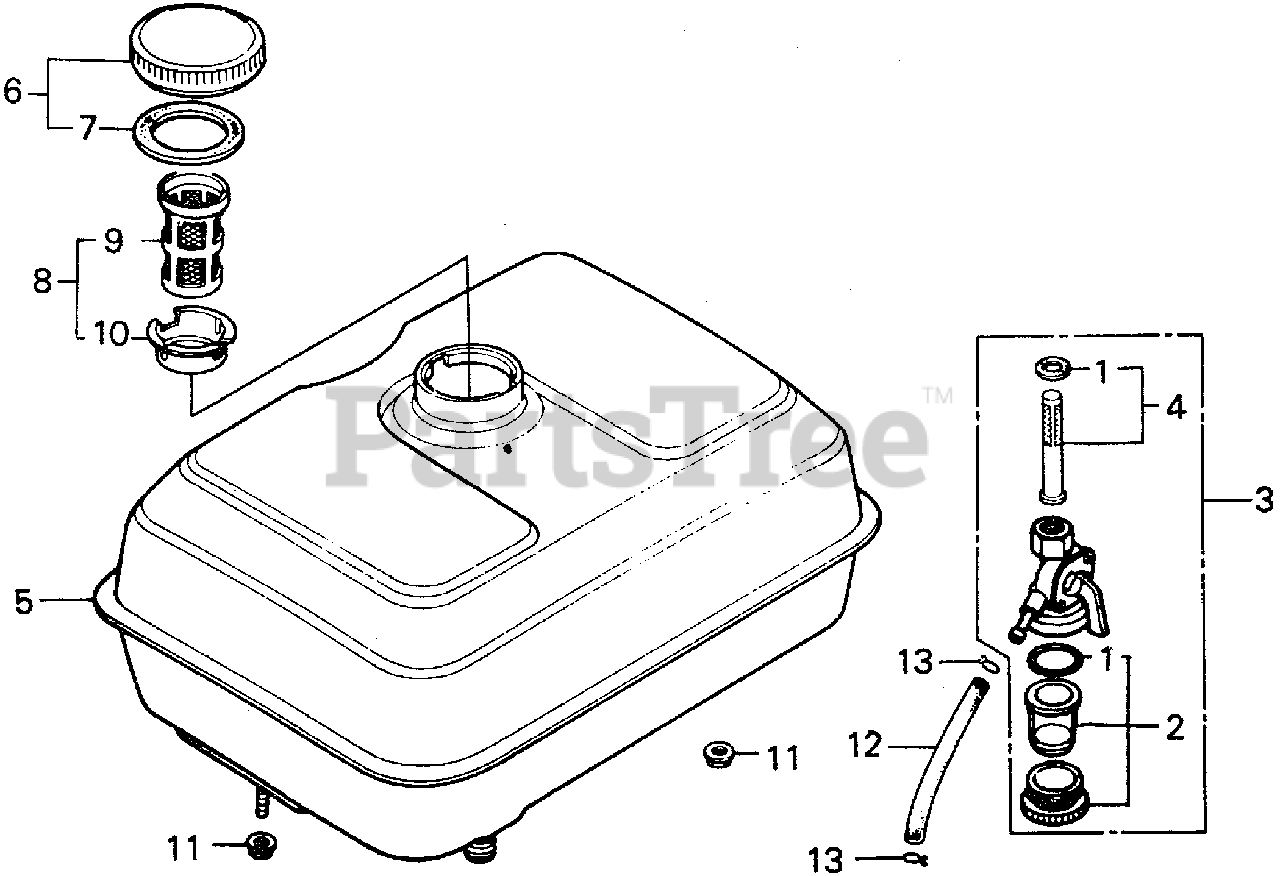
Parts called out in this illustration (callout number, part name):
1	GASKET SET, PETCOCK
2	CUP, FUEL STRAINER
2	CUP SET, FUEL STRAINER
3	PETCOCK ASSY.
4	SCREEN SET
5	TANK, FUEL *NH31* (MCKINLEY WHITE)
5	TANK, FUEL
6	CAP, FUEL FILLER
6	CAP, FUEL FILLER (BLACK)
7	GASKET, FUEL FILLER CAP
7	GASKET, FUEL FILLER CAP (39X58X3)
8	FILTER, FUEL (NOT AVAILABLE)
9	FILTER, FUEL (NOT AVAILABLE)
9	FILTER, FUEL
10	HOLDER, FUEL FILTER
11	NUT, FLANGE (6MM)
12	BULK HOSE, FUEL (4.5X3000) (4.5X65)
12	BULK HOSE, FUEL (4.5X3000) (4.5X70)
13	CLIP, TUBE (B8)
